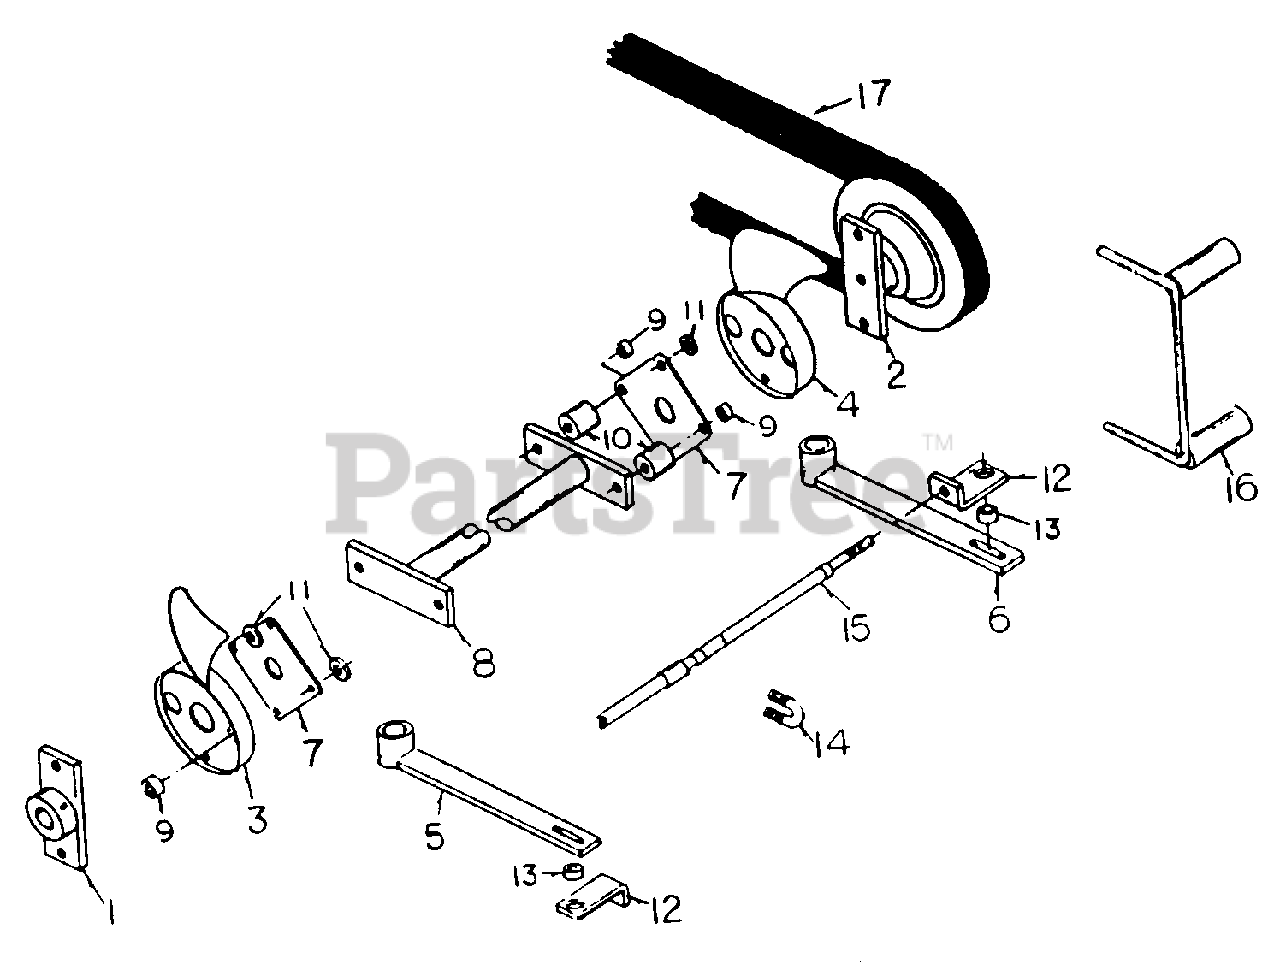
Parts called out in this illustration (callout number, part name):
1	Hub w/Drive Plate
2	Pulley w/Drive Plate
5	Transmission, LH
6	Transmission, RH
7	Drive Plate
8	Transmission Cross Shaft
11	Washer, 1/4", 10 Ga.
12	Steering Cable End
13	Bushing, Steering Lever
14	Steering Cable Clamp
15	Steering Cable
16	Belt Retainer, Transmission
